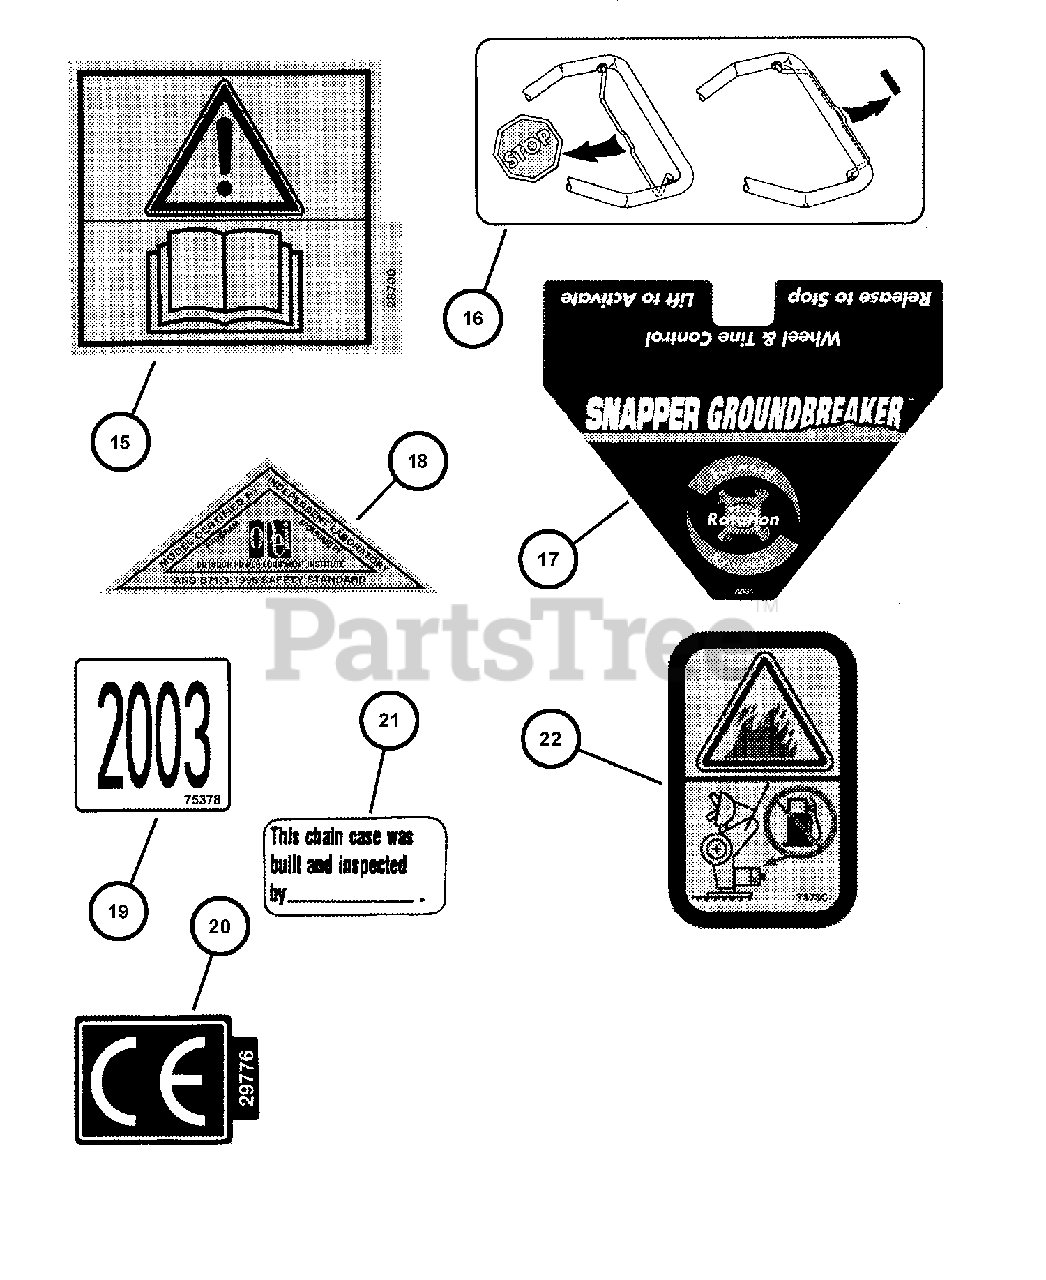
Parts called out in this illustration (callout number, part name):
15	DECAL, Chute/Read Manual (Euro)
16	DECAL, OPC Tiller (Euro)
17	DECAL, Dash Panel (Euro)
18	DECAL, OPEI Tiller
19	DECAL, 2003 Year of Manufacture
20	DECAL, European Community
21	DECAL, Chain Case Inspected By
22	DECAL, Fuel Safety Tiller
